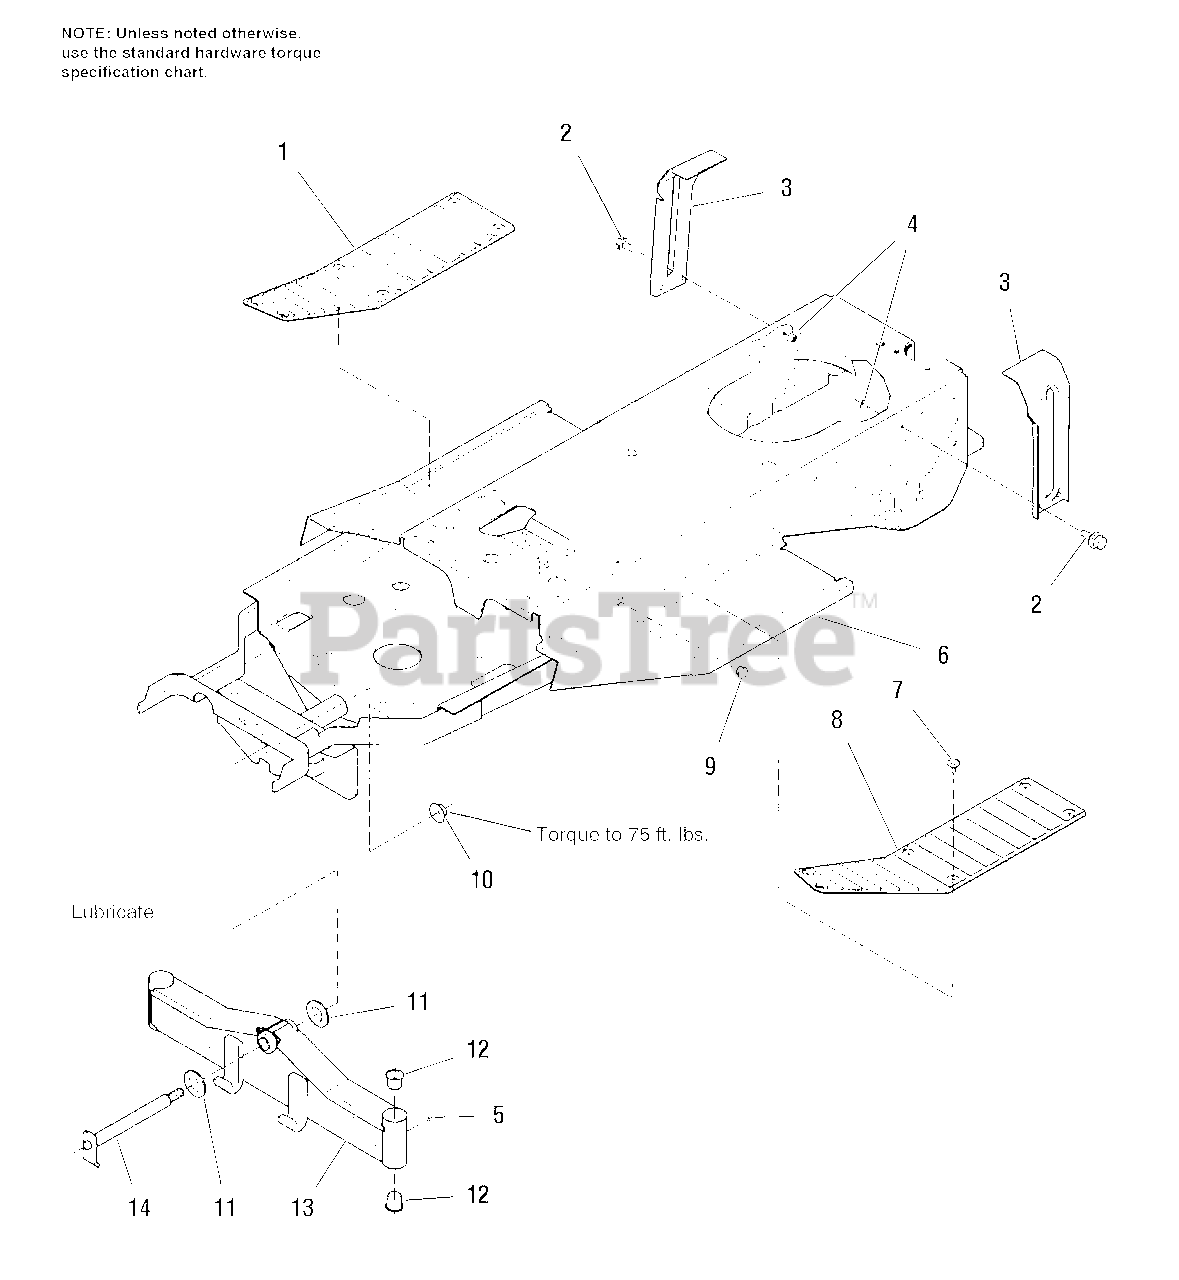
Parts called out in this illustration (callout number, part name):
1	PAD, Footrest, RH
2	CAPSCREW, Hex, Flange, Whizlock, 3/8-16 x 1
3	SUPPORT, Seat
4	NUT, Hex, Esna, Lock, 3/8-16
5	GREASE FITTING
6	FRAME ASSY.
7	FASTENER, Panel
8	PAD, Footrest, LH
10	NUT, Hex, Full, Lock, 3/4-16
11	WASHER
13	AXLE ASSY., Front
14	AXLE PIVOT ASSY.
